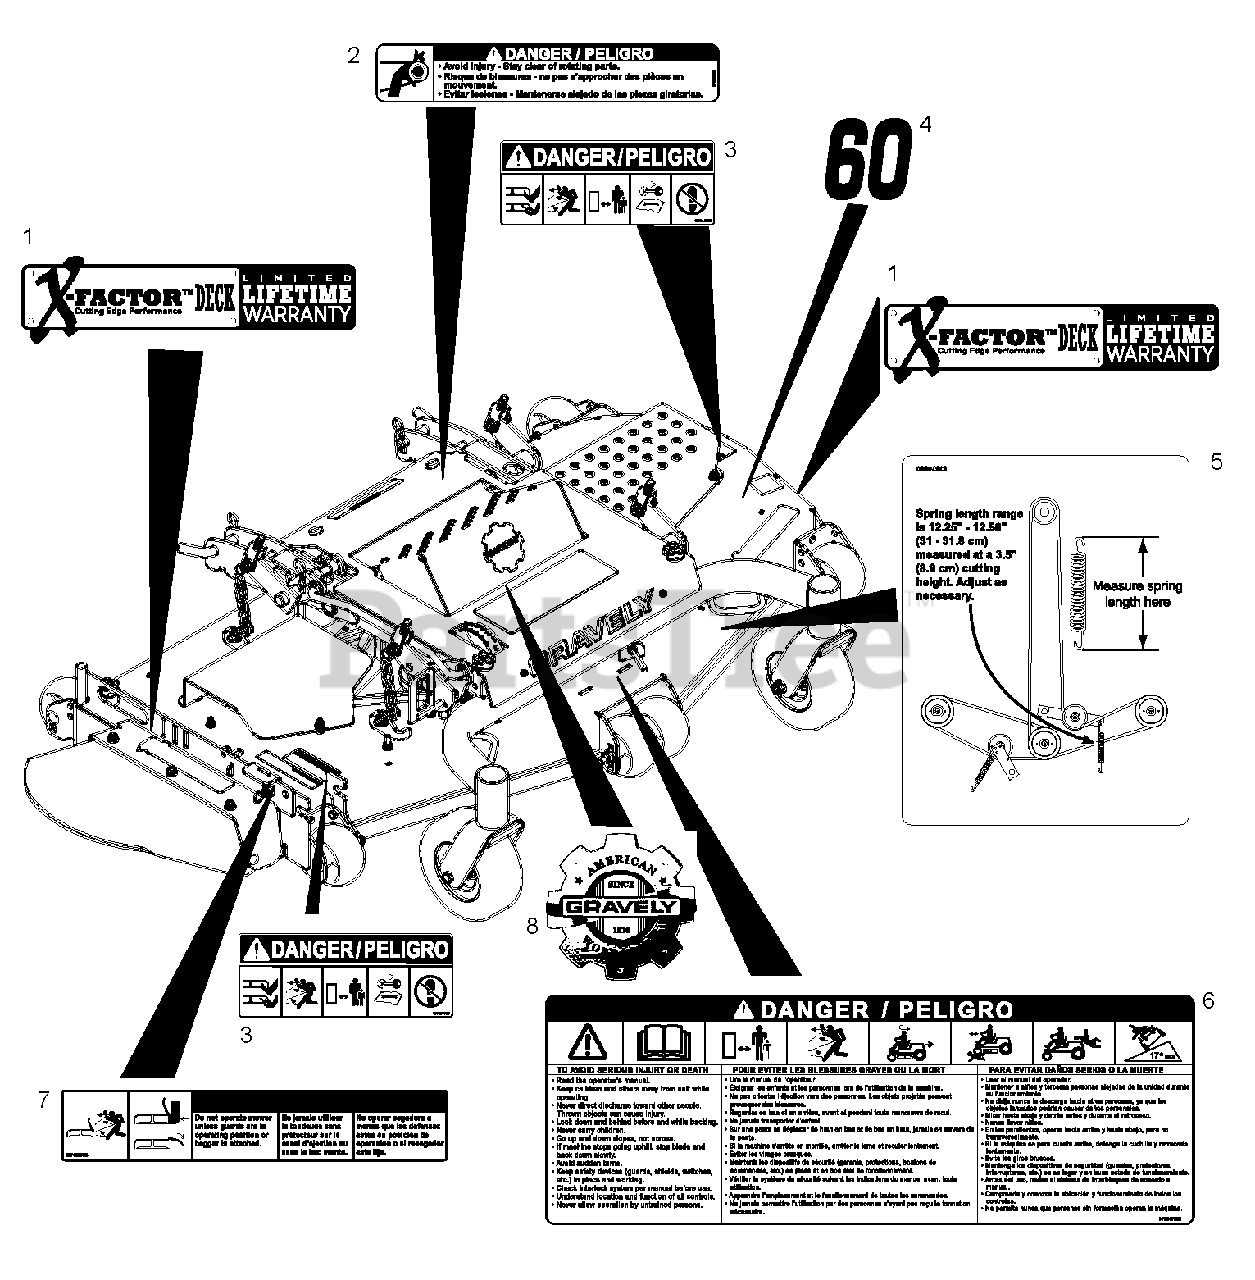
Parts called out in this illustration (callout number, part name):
1	Decal, X-Factor
2	Decal, Danger Rotating Parts
3	Decal, Mower Pan Danger
4	Decal, 60
5	Decal, Belt Diagram
6	Decal, Warning
7	Decal, Warning
8	Decal, Gravely Heritage
